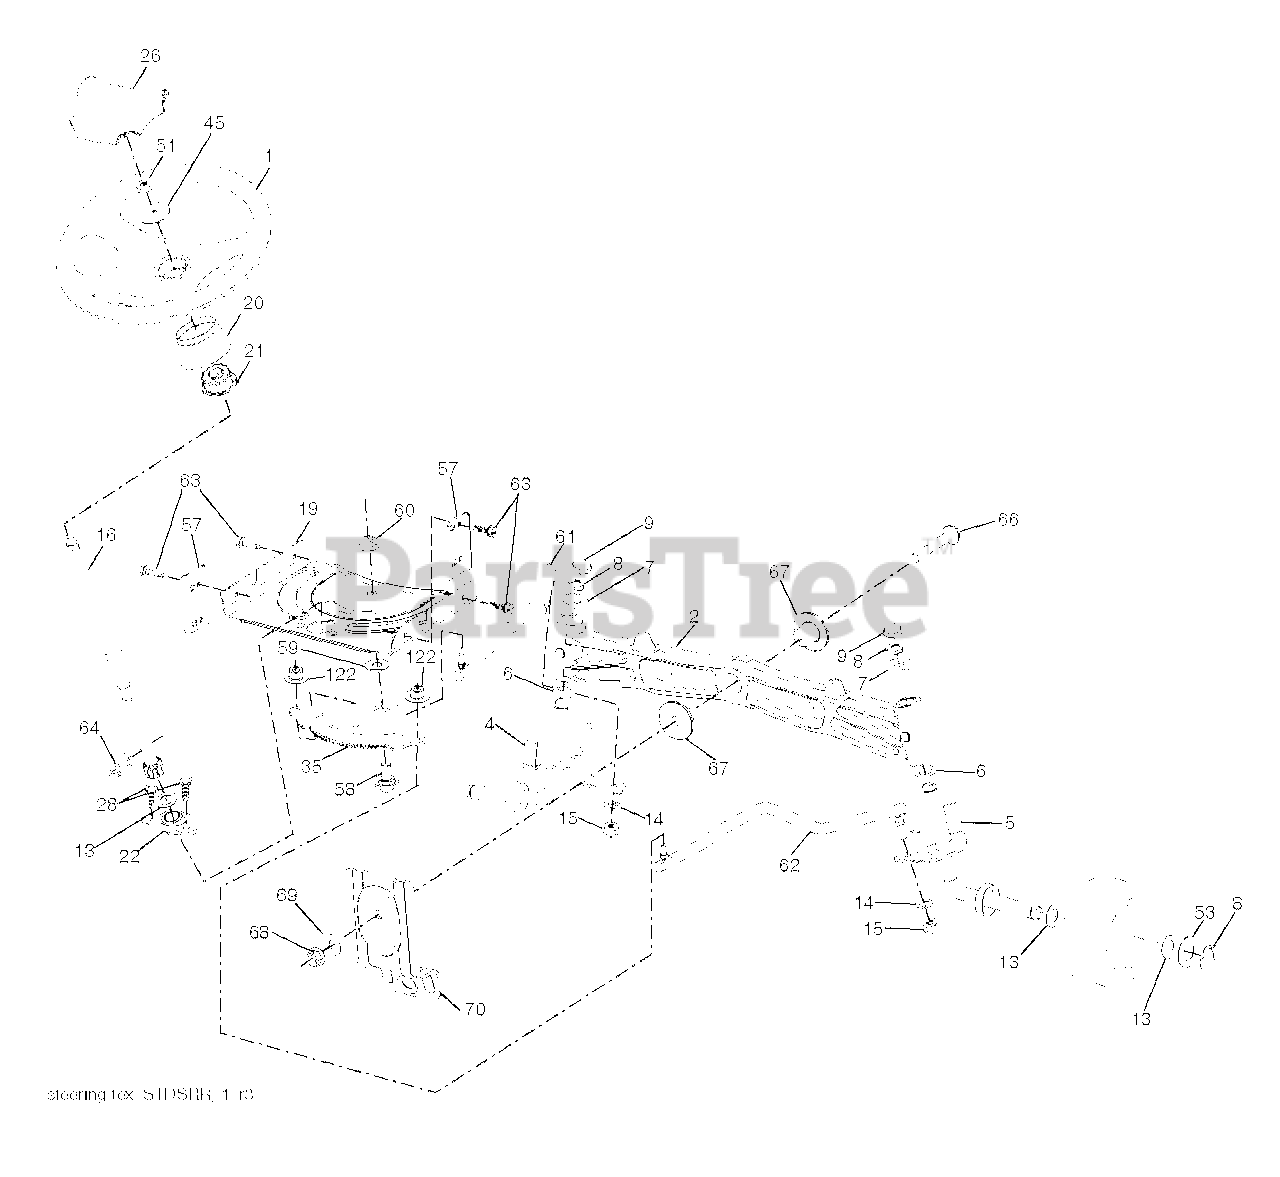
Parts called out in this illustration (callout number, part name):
1	WHEEL.STEERING.MLT.BR.YEL/OVRM
2	AXLE.CAST.IRON
4	SPINDLE.WELDED.LH.15"TEX
5	SPINDLE.WELDED.RH.15"T
8	RING CLIP
9	CAP.SPINDLE.BLACK
14	WASHER, LOCK 3/8
15	NUT CROWNLOCK 3/8-24
16	SHAFT, STEERING
19	PLATE.STEER.DDL.NLT/NG
20	BOOT, STEERING
21	ADAPTER, WHEEL STNG..
22	STEERING.SUPT.LOWER.
26	CAP.WHL.STRNG.MULTI.BRND.YEL
28	SCREW, 3/8-16X3/4
35	GEAR.SECTOR.PLATE.DDL.
45	WASHER 9/16"ID, 2 3/8""OD
51	NUT.HEX.1/2-20
53	WASHER.HARDENED
57	BRACKET.UPSTOP.TEX
58	BOLT.SHOULDER.SECTOR.P
59	WASHER.THURST.SECTOR.S
60	NUT FLANGE LOCK 5/8-11
61	DRAGLINK.LH.BALLSTUD.D
62	DRAGLINK.RH.BALLSTUD.D
63	SCREW
64	RETAINER.CLIP.SPRING.S
66	BOLT HEX FGHD 7/16-14 X 3 SERR
67	BUSHING.PM.FRONT AXLE
68	NUT.LOCK.FLANGE.7/16
69	WASHER.1.5X.505X.118
70	BRKT.DECK.SUSPENSION.F
122	CAP.GEAR.SECTOR.TEX
